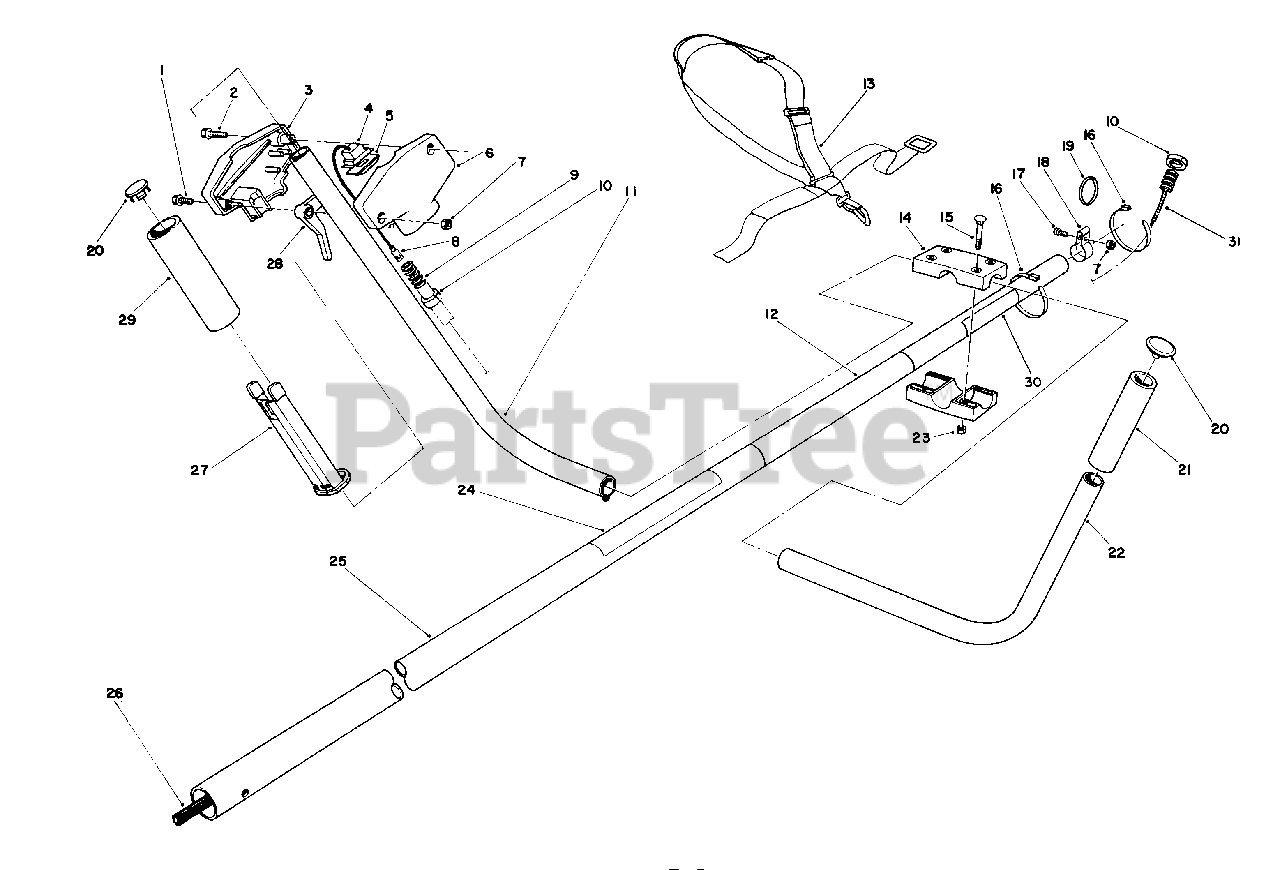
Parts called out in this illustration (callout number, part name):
1	Screw-Hex. Hd.
2	Screw-Hex. Hd.
3	Housing-R.H.
5	Cap-Switch
6	Housing-L.H.
7	Nut-Lock
9	Cover-Cable
11	Tube-Handle R.H.
12	Decal-Danger
13	Harness-Shoulder/Waist
14	Clamp-Bull Horn
15	Bolt-Carriage
16	Tie-Cable
17	Screw-Machine Hd.
18	Clamp-Harness
19	Ring-Harness
20	Plug-Button
21	Grip-Handle L.H.
22	Tube-Handle L.H.
23	Nut-Lock
24	Decal-TC 5010
25	Tube Assembly
26	Shaft-Drive
28	Lever-Throttle
29	Grip-Handle L.H.
30	Decal-Instruction
31	Cable-Throttle
